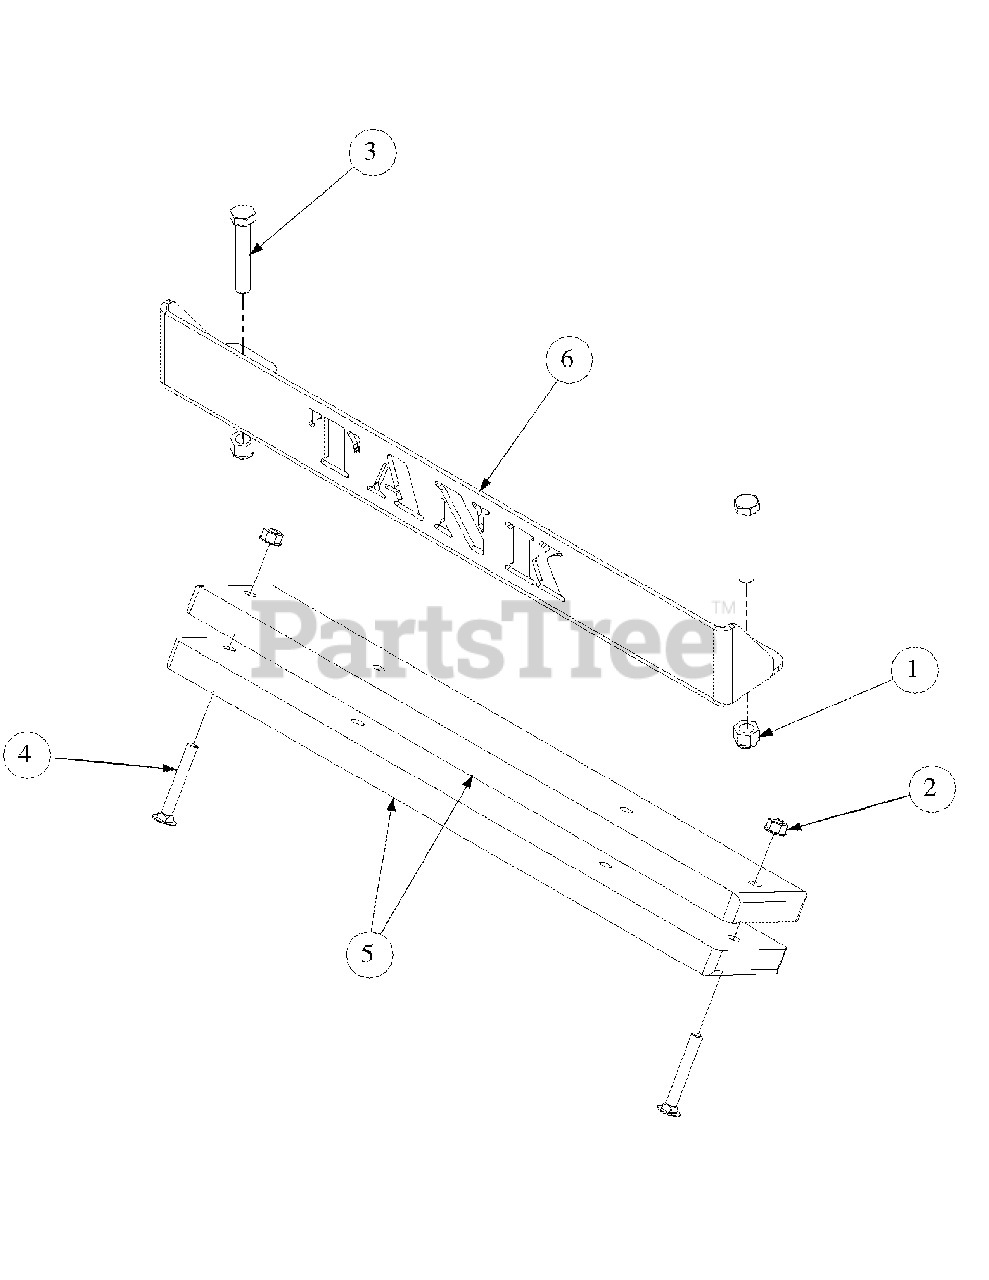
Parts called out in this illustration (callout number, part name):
1	Hex Nut, 1/2-13, Insert Lock
2	Nut, Hex 3/8-16 Flange Lock
3	HHCS, 1/2-13, 3.00
4	Carriage Bolt, 3/8-16, 2.75
5	Bar, Weight
6	Rear Bumper Plate
